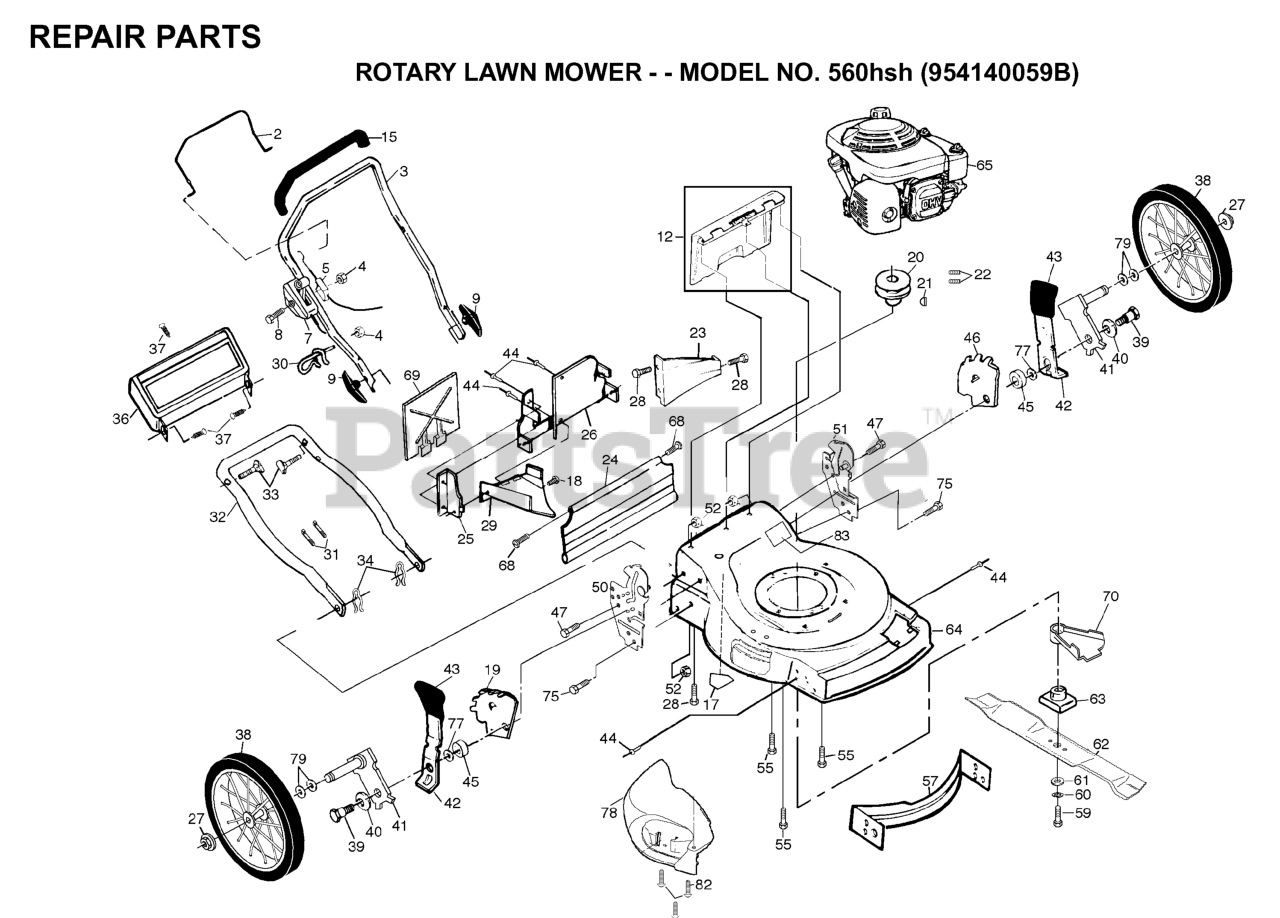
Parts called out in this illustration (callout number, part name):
2	BAIL.CONTROL.WIRE.STD.COMF.BLK
4	NUT
5	CABLE ASSEMBLY
8	SCREW 1/4-20 X 2.12
9	HANDLE KNOB
15	GRIP.HANDLE.FOAM
17	DECAL HYT
18	SCREW.HXTAP.10-24
19	WHL ADJ BRKT LF/RR
20	ENGINE.PULLEY.FWG
21	HI PRO KEY PM WSL
23	REAR BAFFLE
24	REAR SKIRT
25	SIDE BAFFLE
26	BACK PLATE
27	HEX FLANGE LOCKNT
29	DISCHARGE BAFFLE
30	ROPE GUIDE
31	TIE GUIDE
32	HANDLE, LOWER
33	HANDLE BOLT
34	HAIRPIN COTTER
36	TRIM PLATE
38	WHEEL TIRE PM
39	BOLT
42	SELECTOR SPRING
43	SELECTOR KNOB
44	RIVET BLIND
45	RP SPACER HT ADJ
46	WHL ADJ BRKT RF/LR
47	SELF-TAPPING SCREW 5/16-18X3/4
51	BRACKET
52	LOCKNUT PM
55	BOLT 3/8-16X1-1/8
57	BAFFLE
59	SCREW, HEX HD 3/8-24 X 1-3/8
60	LOCKWASHER
61	WASHER,HARDEN
63	BLADE ADAPTOR
68	HINGE SCREW
69	MULCHER PLATE
70	DEBRIS SHIELD
77	WASHER.FLAT.1/2
79	WAVE WASHER
82	SCREW.PAN.HEAD.#10
83	WARNING DECAL
